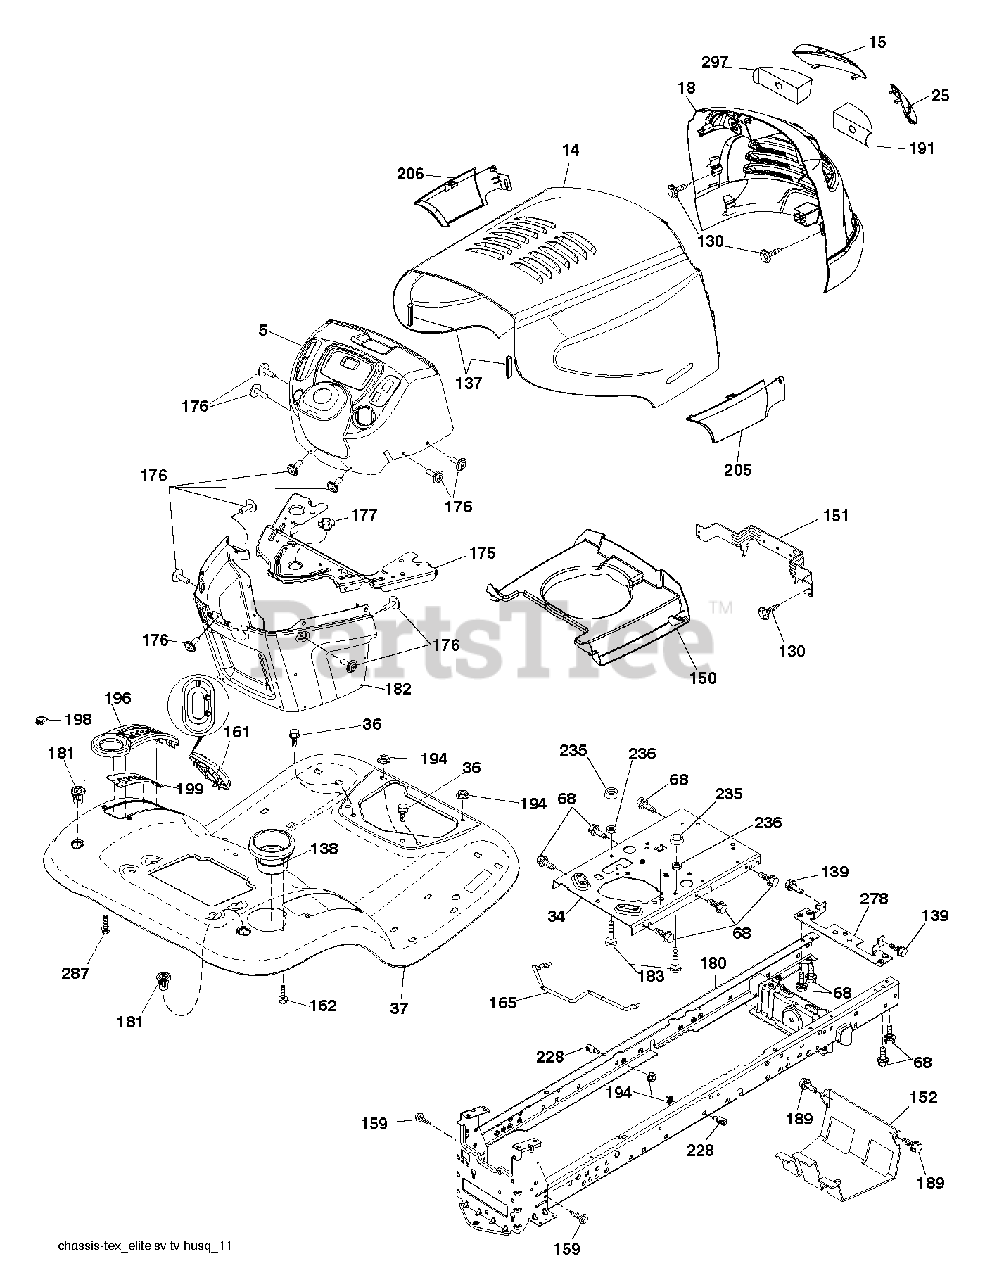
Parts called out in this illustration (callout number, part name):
5	DASH UPPER
14	HOOD.PNT.ELITE.TVENT.SVENT.SSK
18	GRILLE.ELITE HUSQ.BLACK.DL.
34	PLATE.ENGINE.WELDED.CHASSIS
36	SCREW 5/16"
68	SCREW LT
130	SCREW.#10 X 0.750.BOS (2 2)
137	BUMPER.HOOD.LARGE.1.75"
138	CUPHOLDER.TL.TEX.BLACK
139	BOLT, SHOULDER 5/16-18
150	AIR DUCT
151	BRACKET PIVOT
152	SHIELD.BROWNING.W/TEX
159	SCREW, 3/8-16X3/4
161	WINDOW.FUEL.LT.TEX.BLACK
162	SCREW.HI-LO.CONSOLE
165	SUPPORT.TANK.REAR.W/TEX
175	CROSSMEMBER.LT
176	SCREW.#10-24X5/8.RN.QU
177	BUSHING,STEERING
180	CHASSIS
181	FEND/FTRST.PCH.CPH.NFW
182	DASH.LOWER.LT.CCS
183	BOLT.5/16-18X1-1/4 FULL THD
189	SCREW
191	INSERT.REFLECTIVE.RH.
194	NUT LOCK HEX FLANGE 5/16-18
196	CONSOLE.ASM.DECKLFT.BL/RBT.TLT
198	INDICATOR.DECK.LIFT.RED
199	Deck Lift Plate, Husq Lt
205	SKIRT.SIDE.RH.ELITE.HUSQ.428
206	SKIRT.SIDE.LH.ELITE.HUSQ.BLACK
228	STUD.FASTNER.W/ANTI-ROTATE
235	SPACER FENDER
236	NUT.CENTERLOCK.5/16-
278	BRKT.HOOD/MUFF.STEALTH
287	SCREW 1/4X20
297	INSERT LENS
